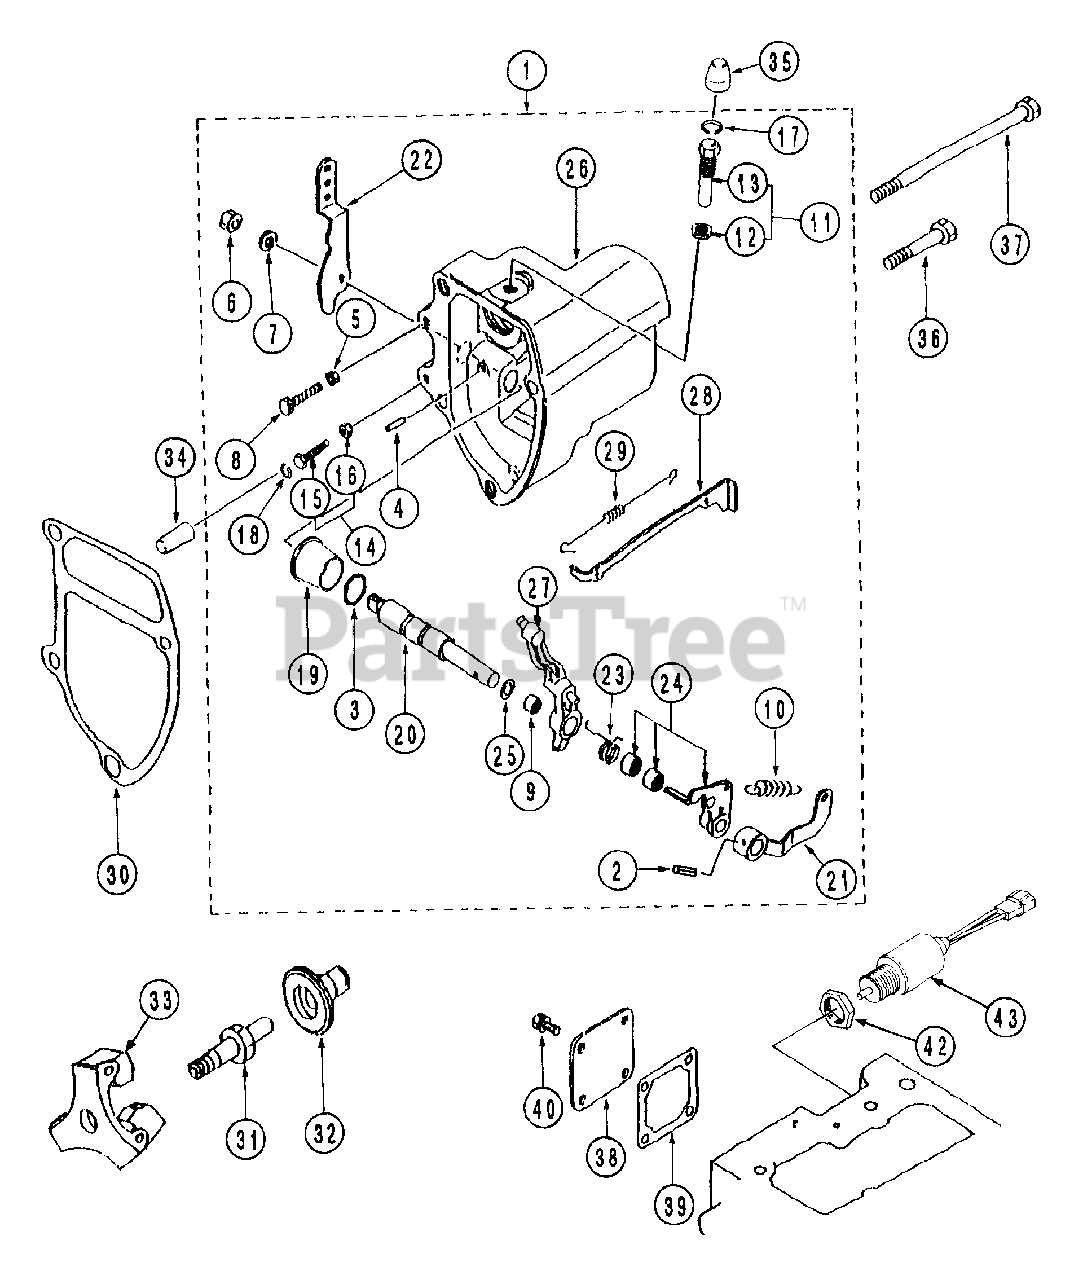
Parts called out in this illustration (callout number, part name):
1	Case Ass'y., Governor
2	Pin, Spring
4	Pin, Grooved
7	Washer, Spring
8	Bolt, Speed Set
9	Bearing, Needle
11	Screw Ass'y., Rack Set
12	Nut, Torque Set
13	Screw, Rack Set
14	Bolt Ass'y., High Speed
15	Bolt, High Speed Set
16	Nut, High Speed Set
17	C-Ring, Torque Set
18	C-Ring, High Speed Set
19	Cover, Governor Shaft
20	Shaft, Governor
21	Lever, Gov. Spring
23	Spring, Start
24	Lever Ass'y., Tension
25	Shim, Governor Shaft
26	Case, Governor
27	Lever Ass'y., Governor
29	Spring, Tie-Rod
30	Gasket, Governor Case
31	Shaft, Sliding, Sleeve
32	Sleeve, Sliding
33	Weight Ass'y., Governor
34	Cover High Speed Set
35	Cover, Torque Set
37	Bolt, Gov. Case
38	Cover, Tie Rod
39	Gasket, Tie Rod Cover
40	Bolt, W/Washer
43	Solenoid Ass'y.
